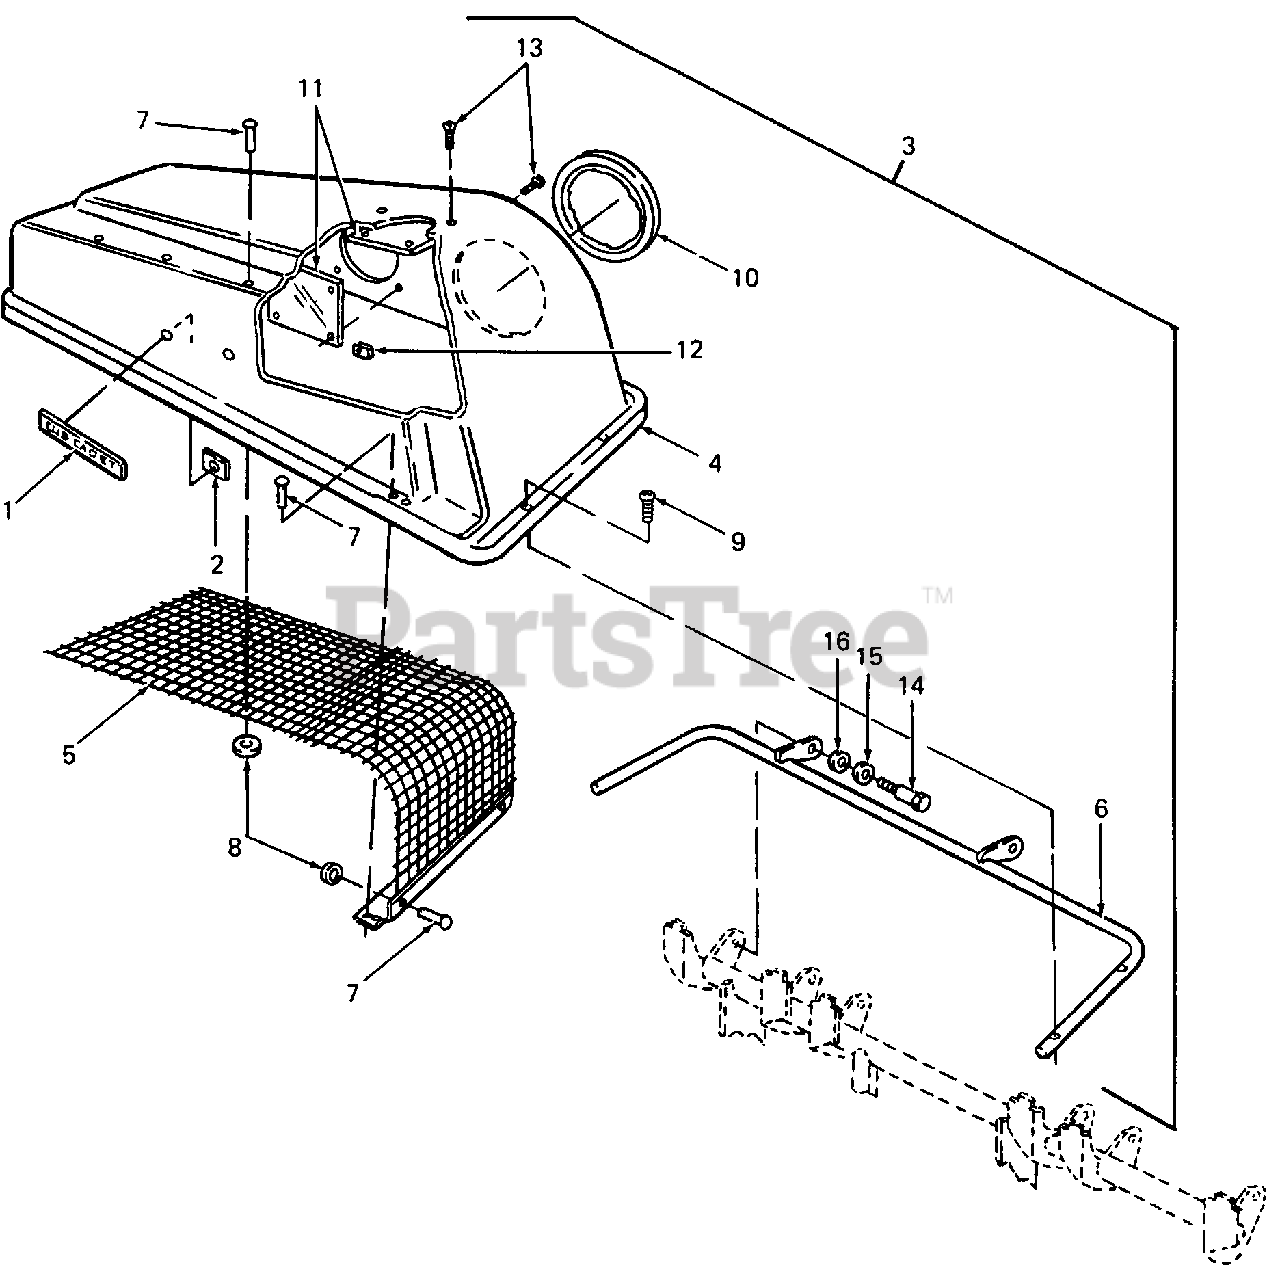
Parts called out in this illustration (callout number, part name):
1	Plaque, Logo w/Studs
2	Nut, Push-On Speed
3	Cover Assy, Grass Catcher
8	Washer, Flat, .218 X .62 X .063 Thk
9	Screw, Hex Wash Hd Tapp, 1/4 X .50 Lg
10	Seal, Tube, 7.1 ID
11	Plate, Plastic, 1/8 Thk X 5.62 Sq
12	Nut, U-Type Speed
13	Screw, Truss Mach., #10 X .50 Lg
14	Screw, Shld
15	Washer, Flat, .510 X .75 X .033 Thk
16	Washer, Bell, .515 X 1.14
